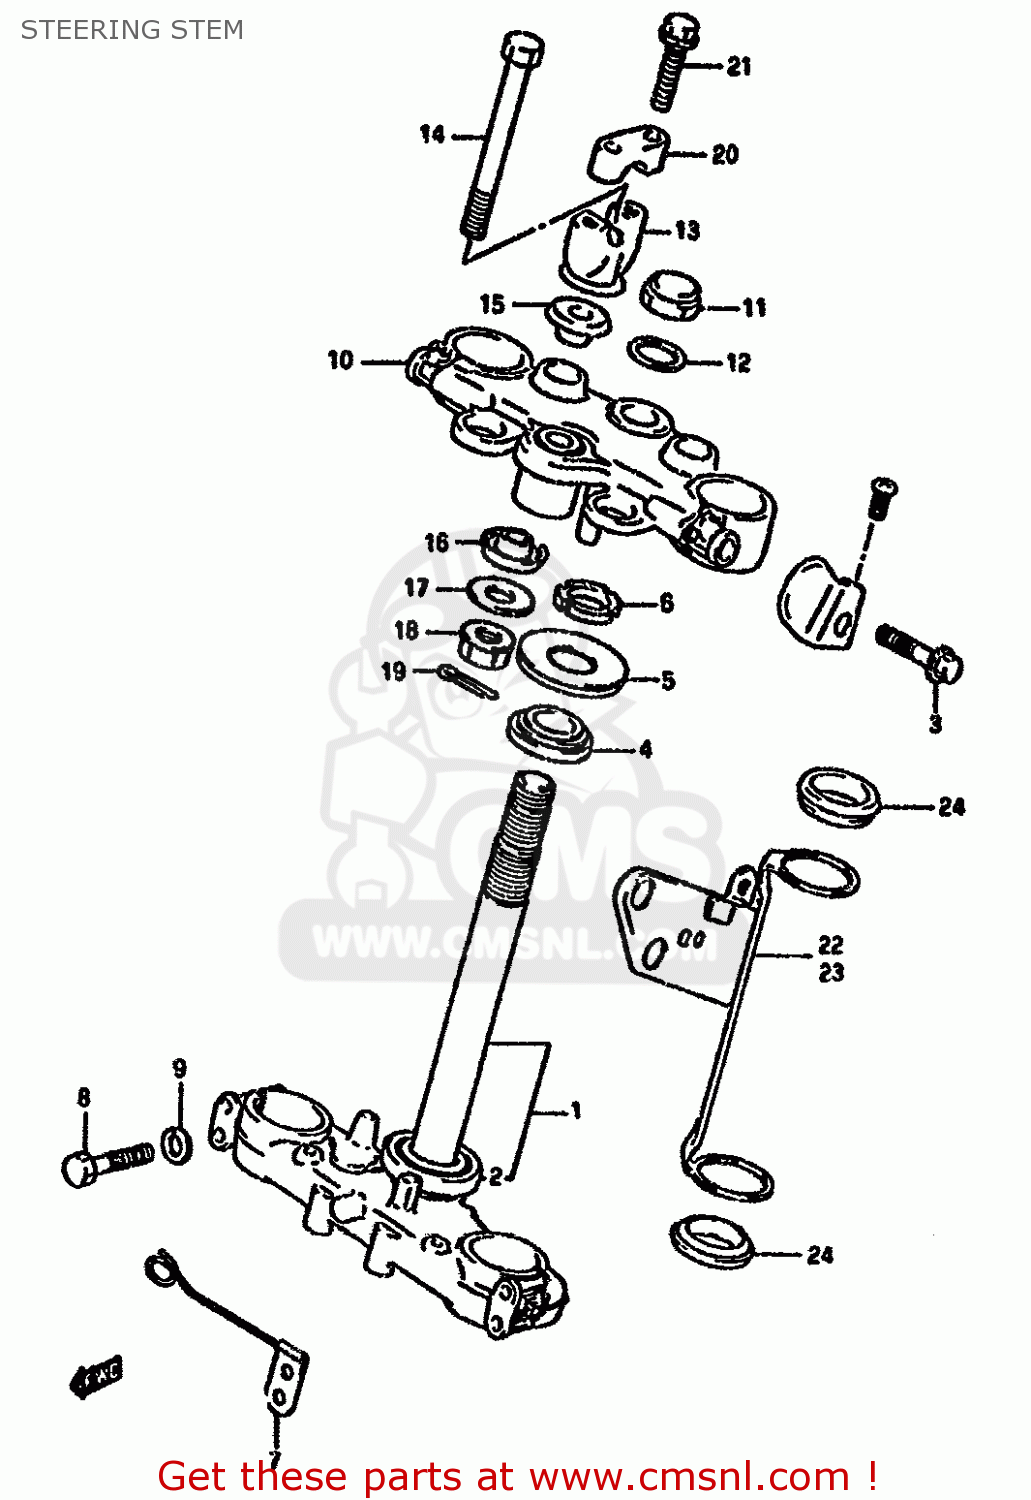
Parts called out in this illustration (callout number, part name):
1	STEM,STEERING
2	BEARING(30X55X17)
3	BOLT 10X45
4	TAPER,ROLLER BEARING
5	SEAL,STEERING UPR DUST
6	NUT,STEERING STEM
7	GUIDE, SPEEDOMETER CABLE
8	BOLT 8X45
9	WASHER,LOCK
10	HEAD,STEERING STEM
11	NUT,CAP
12	WASHER(22.5X32X1.6)
13	HOLDER,HANDLE LWR
14	BOLT
15	DAMPER,UPR
16	DAMPER,LWR
17	WASHER,HANDLEBAR HOLDER
18	NUT
19	COTTER PIN
20	HOLDER,HANDLE UPR
21	BOLT
22	COVER,FORK,R
23	COVER,FORK,L
24	CUSHION,HEADLAMP BRACKET
